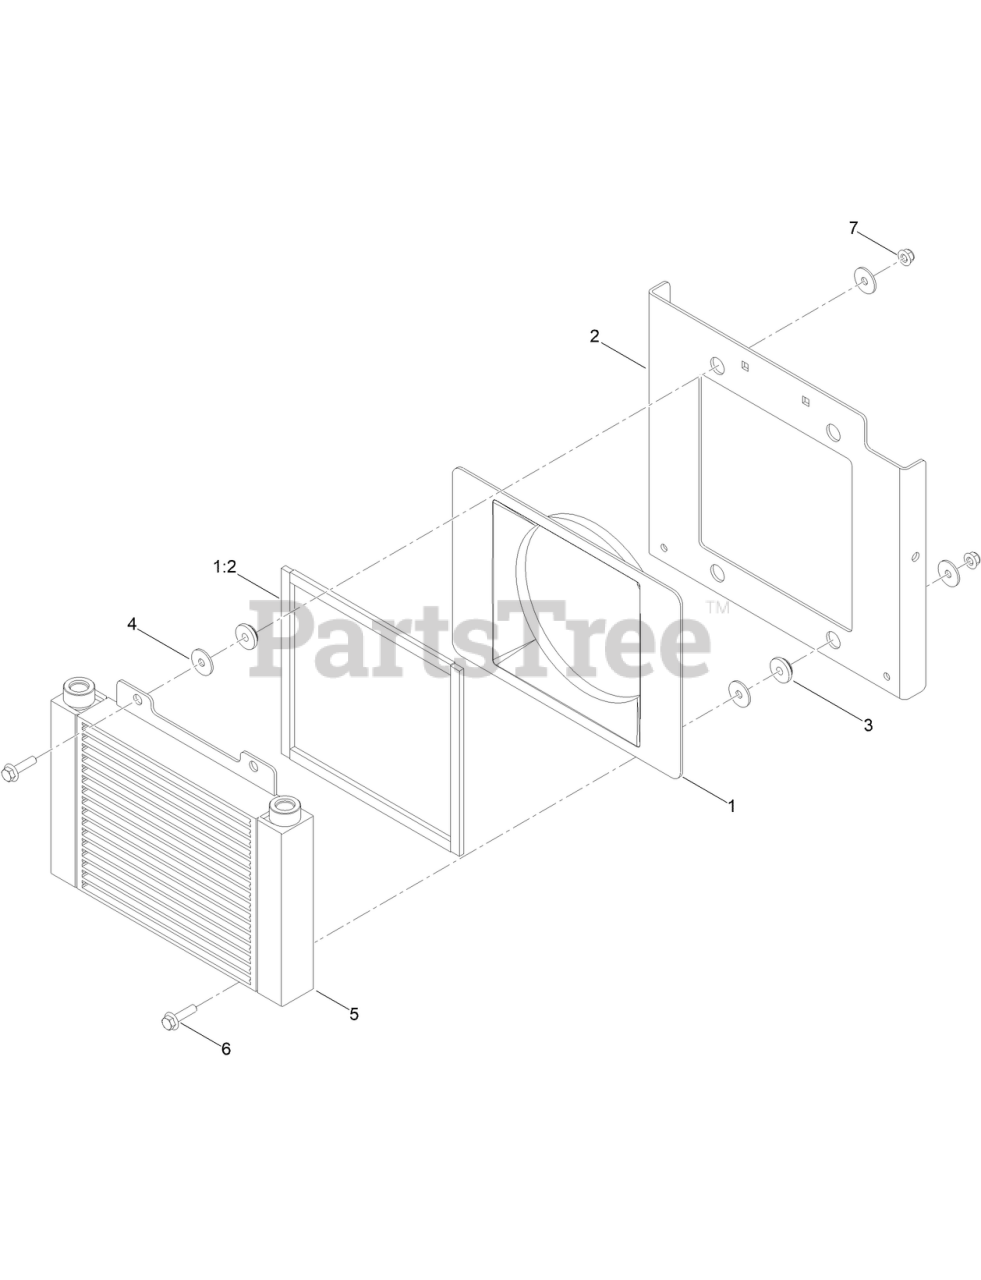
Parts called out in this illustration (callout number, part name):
1	Shroud ASM W/Seals
1:2	SEAL-FOAM
2	BRACKET-SHROUD
4	WASHER-PIVOT
5	COOLER-OIL
6	SCREW-HHF
7	NUT-HF, NI
